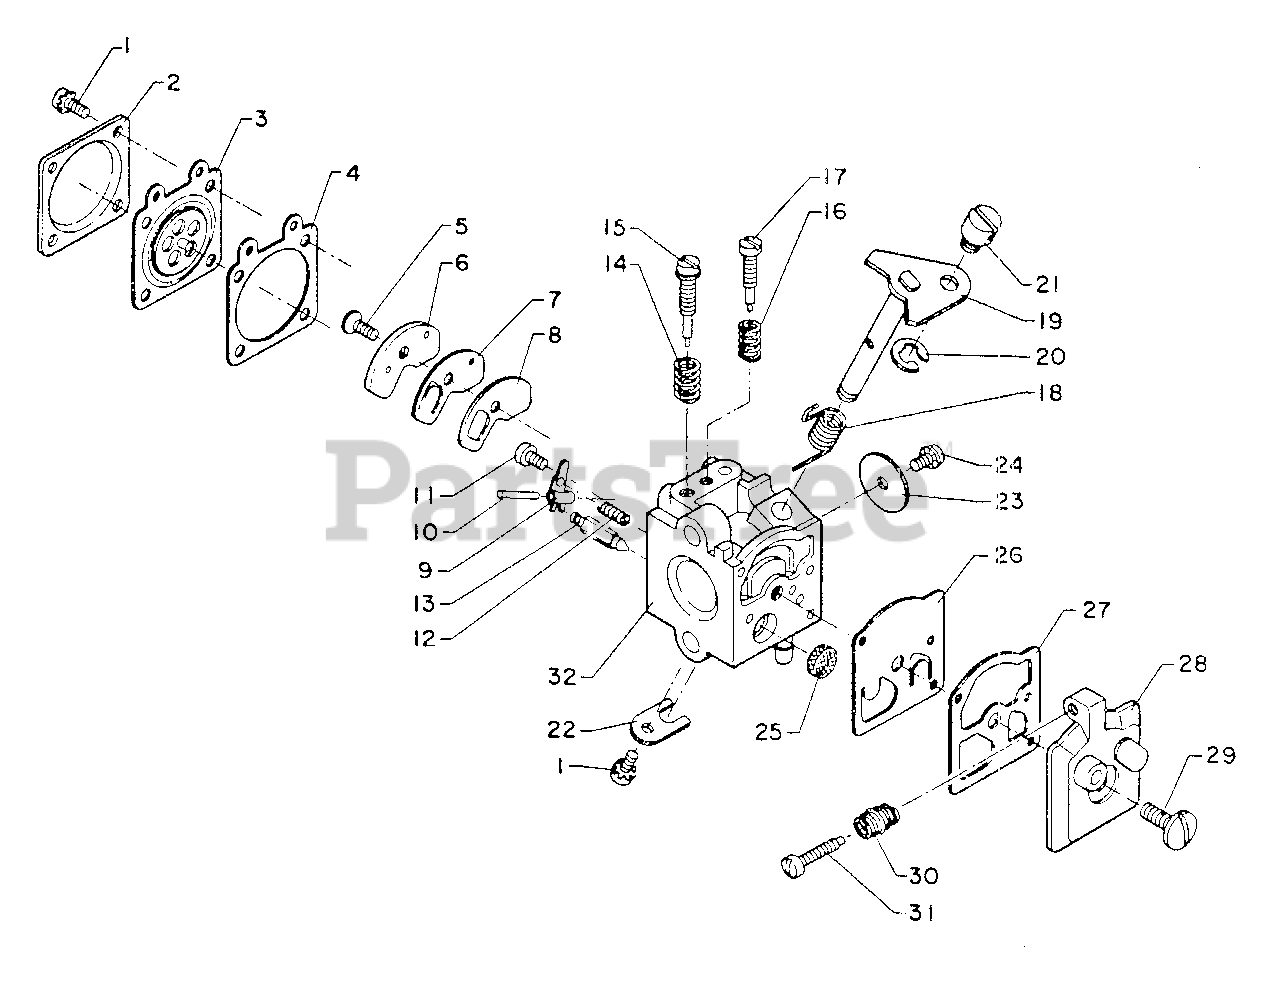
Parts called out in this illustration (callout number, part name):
1	SCREW
2	COVER, METERING
3	DIAPHRAGM, METERING
4	GASKET, METERING
5	SCREW, CIRCUIT PLATE
6	PLATE, CIRCUIT
7	DIAPHRAGM, CIRCUIT PLATE
8	GASKET, CIRCUIT PLATE
9	LEVER, METERING
10	PIN, METERING LEVER
11	SCREW, METERING LEVER PIN
12	SPRING, METERING LEVER
13	VALVE, INLET NEEDLE
14	SPRING, HIGH SPEED NEEDLE
15	NEEDLE - HIGH SPEED
16	SPRING, IDLE ADJUST
17	NEEDLE - LOW SPEED
18	SPRING, THROTTLE RETURN
19	SHAFT, THROTTLE
20	RING, RETAINING
22	CLIP, THROTTLE SHAFT
23	VALVE, THROTTLE
25	STRAINER
26	DIAPHRAGM, PURGE
27	GASKET, PURGE
28	COVER, PUMP
29	SCREW, PUMP COVER
30	SPRING, IDLE ADJUST
31	SCREW, IDLE ADJUST
32	BODY, CARBURETOR
